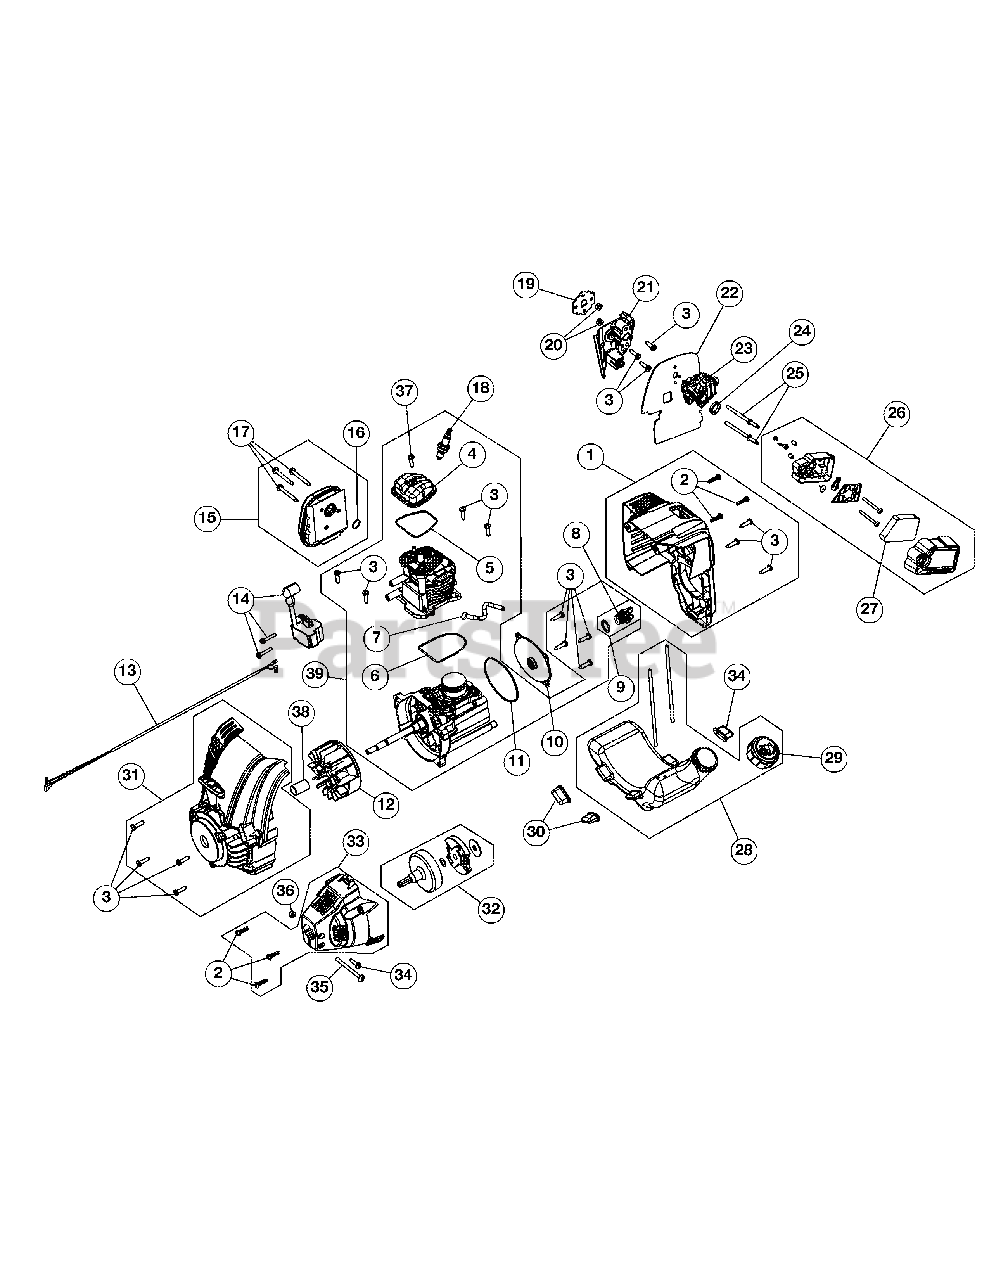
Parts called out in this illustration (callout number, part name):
1	Engine Cover Assembly (Incl. 2 & 3)
2	Cover Screw
3	Starter Screw
4	Rocker Cover
5	Rocker Cover O-Ring
6	Cylinder O-Ring
7	Breather Hose
8	Oil Plug (Incl. 9)
9	Oil Plug O-Ring
10	Crankcase Cover
11	Crankcase Cover O-ring
12	Flywheel Assembly
13	Lead Wires
14	Module Assembly
15	Muffler Assembly (Incl. 16 & 17)
16	Muffler Gasket
17	Muffler Screw
18	Spark Plug
19	Insulator Gasket
21	Insulator
22	Carburetor Gasket
23	Carburetor w/Primer
24	Carburetor O-Ring
25	Air Filter Mounting Screw
26	Air Cleaner Cover Assembly (Incl. 27)
27	Air Filter
28	Fuel Tank Assembly w/Fuel Lines (Incl. 29)
29	Fuel Cap
30	Fuel Tank Pads
31	Starter Housing Assembly (Incl. 3)
32	Clutch Assembly
33	Clutch Cover (Incl. 2)
34	Anti-Rotation Screw
35	Clamp Screw
37	Rocker Cover Screw
38	Spacer
39	Shortblock Assembly
